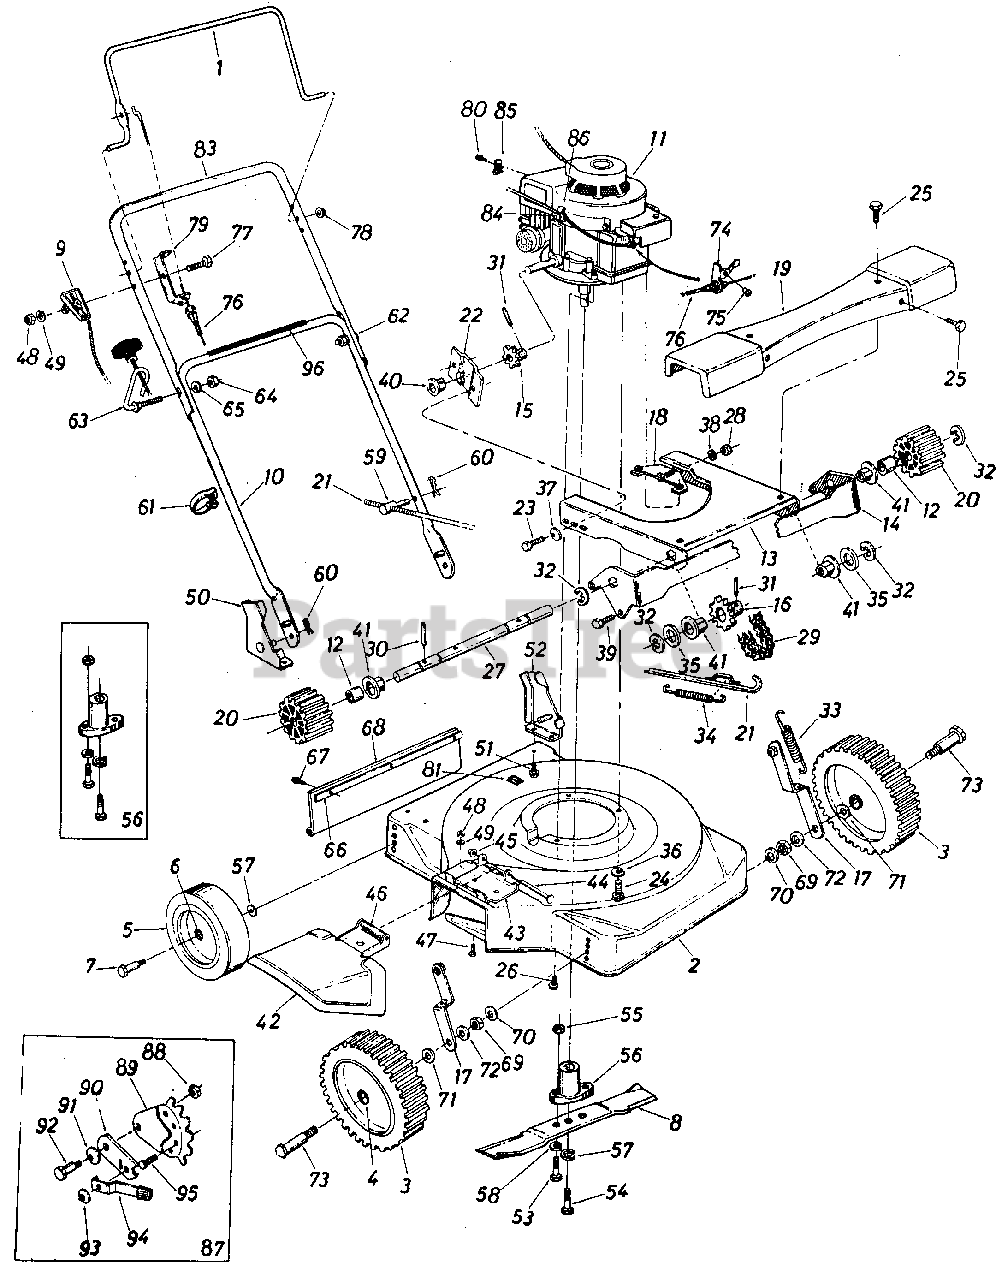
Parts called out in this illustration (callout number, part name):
1	Control Handle-R.H.
4	Flange Brg.
6	Flange Brg. (Plastic)
7	Axle Bolt-Rear
8	Blade 22"
9	Throttle Control Ass'y. Comp.
10	Lower Handle (Chrome)
11	Engine
12	Crank Spacer .632" I.D. x .75" O.D. x .442
13	Pivot Plate
14	Drive Support
15	Sprocket Ass'y.
16	Sprocket Ass'y.
17	Link Ass'y.
18	Engine Bracket Ass'y.
19	Drive Cover
20	Drive Pinion
21	Clutch Rod Ass'y.
22	Bearing Support
23	Hex "B"-Tap Scr. 1/4 x .38" Lg.
24	Hex Bolt 5/16-18 x 1.50" Lg.
25	Hex Wash. Self-Tap Scr. 1/4-20 x .50" Lg.
26	Hex Wash. Hd. TT-Tap Scr. 3/8-16 x 1.00" Lg.
27	Shaft
28	Hex Ins. L-Nut 3/8-24 Thd.
29	#48 Chain 1/2" Pitch x 51 Li n ks
30	Spring Pin Spir. 3116" Dia. x 1.25" Lg.
31	Spring Pin Spir. 3116" Dia. x 1.00" Lg.
32	"E"-Ring for.625" Dia. Shaft
33	Extension Spring .47" O.D. x 2.03" Lg.
34	Extension Spring .50" O.D. x 5.0" Lg.
35	Fl-Wash. .635" I.D. x .93" O.D. x .060
36	L-Wash. 5/16" I.D.
37	Spr.-Wash. .270" I.D. x .57" O.D. x .025
38	Fl-Wash. .385" I.D. x .87" O.D. x .06
39	Shld. Bolt .500" Dia. x .170
40	Flange Brg.
41	Hex Flange Brg. .630" I.D.
42	Chute Deflector Ass'y. Comp.
43	Adapter Plate
44	Pivot Pin
45	Push Nut 1/4' Rod
46	Torsion Spring
47	Hex Bolt 1/4-20 x .50" Lg.*
48	Hex Nut 1/4-20 Thd.*
49	L-Wash. 1/4'1 I.D.*
50	Handle Brkt. Ass'y.-R.H.
51	Hex Wash. Hd. Self-Tap Scr. 5/16-18 x .50" Lg.
52	Handle Brkt. Ass'y.-L.H.
53	Hex Bolt 5/16-24 x 1.00" Lg. (Grade 5)
54	Hex Bolt 3/8-24 x 2.25" Lg. (Grade 5)
55	Hex Nut 5/16-24 Thd.*
56	Blade Adapter Kit
57	Bell-Wash. .400" I.D. x .88" O.D.
58	L-Wash. 5/16" I.D.*
59	Engagement Ferrule
60	Intern. Cot. Pin 5/16" Dia.
61	Cable Tie
62	Curved Carriage Bolt 5/16-18 x 1.38" Lg.
63	Rope Guide Bolt
64	Hex Nut 5/16-18 Thd.*
65	L-Wash. 5/16" I.D.*
66	Retainer Strip
67	Hex Wash. Hd. Self-Tap Scr. 1/4 x.62" Lg.
68	Rear F I ap Ass'y.
69	Hex Cent. L-Nut 3/8-16 Thd.
70	Bell-Wash. .400" I.D. x .88" O.D.
71	Fl-Wash. .531" I.D. x .930" O.D.
72	Fl-Wash. .385" I.D. x .87" O.D.
73	Axle Bolt-Front
74	Cable Brkt.
75	Pop Rivet .156" Dia. x .379
76	Control Cable-49
77	Hex Bolt 1/4-20 x 1.25" Lg.*
78	Cap Speed Nut 5/16" Rod
79	Cable Mounting Brkt.
80	Hex Wash. Hd. Self-Tap Scr. #8 x .38" Lg.
81	Plastic Plug
83	Upper Handle (Chrome)
84	Hex B-Tap Scr. #10 x .38"
85	Casing Clamp
86	Casing Clamp
87	Height Adj. Ass'y. Comp.-L.H.
88	Hex Cent. L-Nut 3/8-16 Thd.
89	Index Plate
90	Pivot Bar
91	Belleville Washer
92	Shld. Bolt
93	Belleville Wash. 3/8" I.D.
94	Spring Lever Ass'y. w/Knob
95	Hex Sems Bolt 3/8-16 x .62" Lg .
96	Instruction Label-Handle
